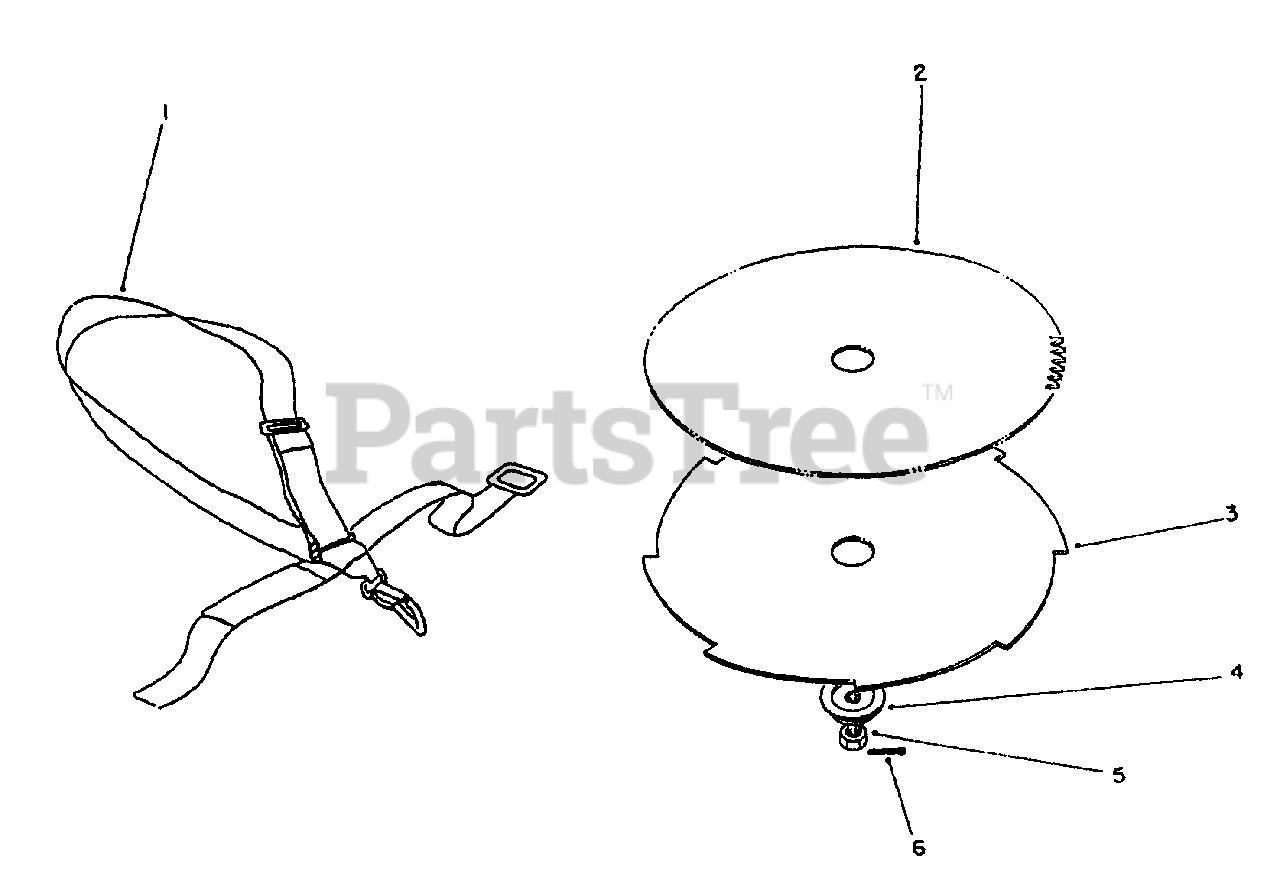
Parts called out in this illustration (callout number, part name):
1	Deluxe Harness
2	8"Dia.Blade Saw (80 Tooth)
3	8"Dia.Blade Brush (8 Tooth)
4	Adapter-Blade
5	Nut L.H.
6	Pin-Cotter
